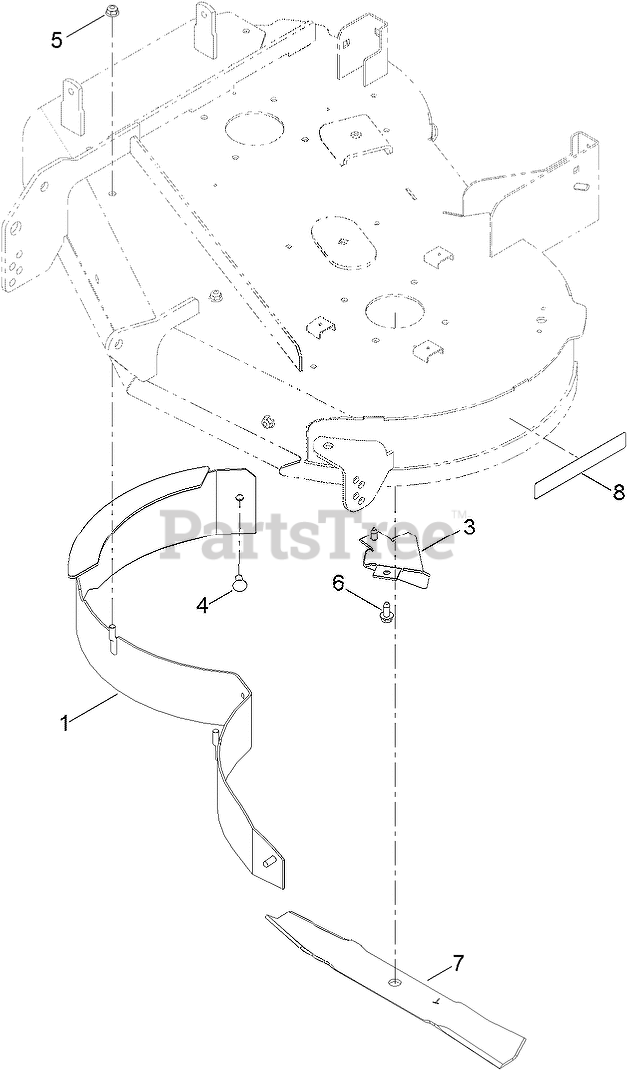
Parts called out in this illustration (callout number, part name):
1	BAFFLE ASM
3	KICKER-FLANGED
4	BOLT-CARR
5	NUT-HF, NI
6	SCREW-HWHTF
7	BLADE-MULCH, 17.50 INCH
8	DECAL-RECYCLER
